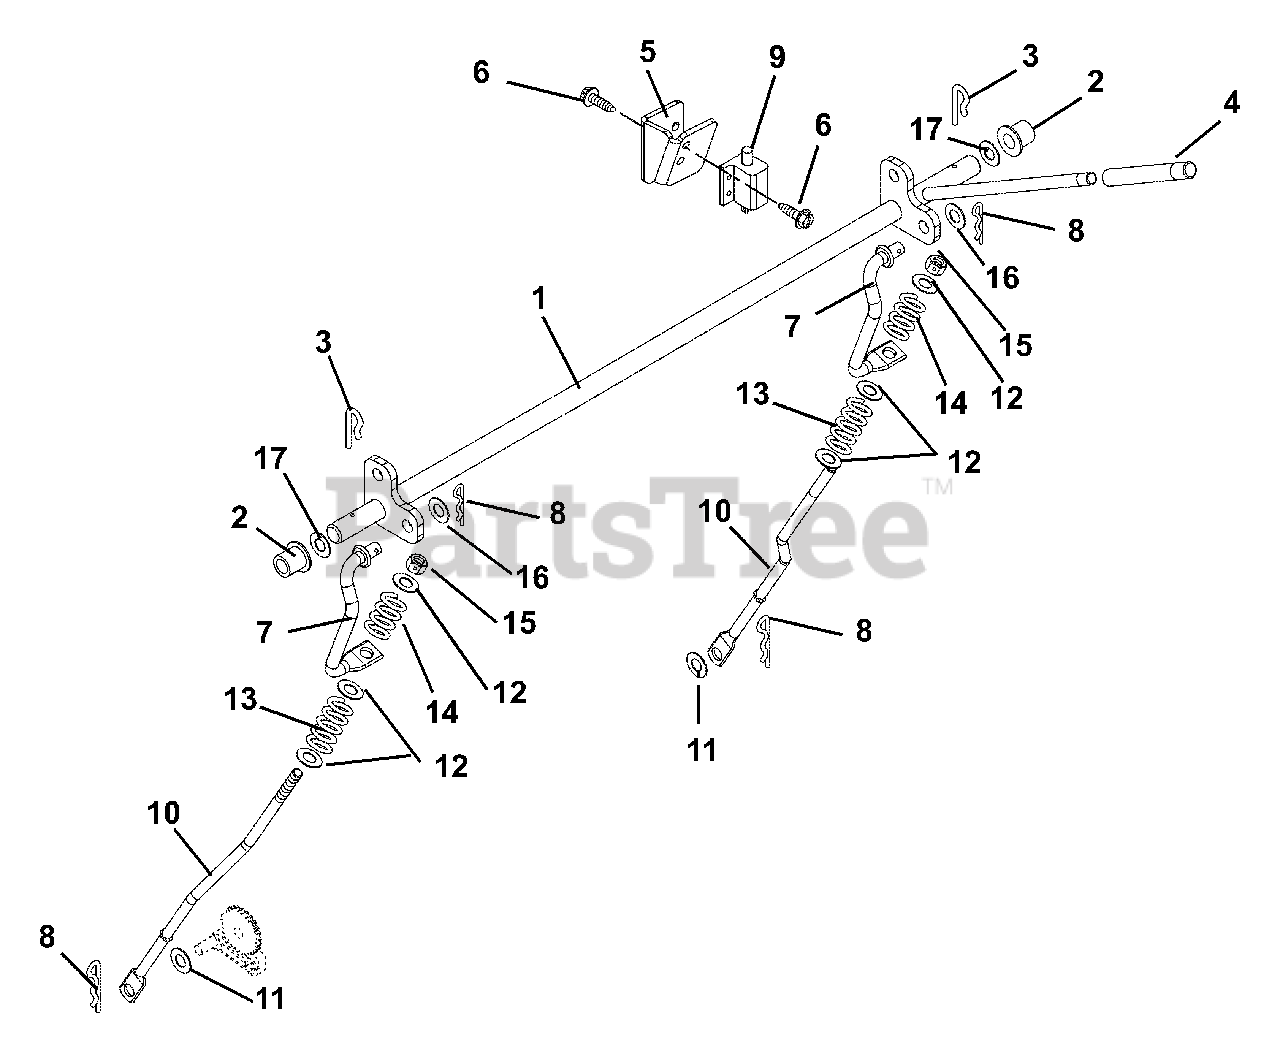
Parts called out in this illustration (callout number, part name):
1	WMT, ZOOM BRAKE ROD
2	BSHG-FLG .630X1.000X.625 NY
3	PIN, SPRING CLIP
4	GRIP,HAND CLUTCH LEVER
5	BRACKET, BRAKE SWITCH
6	@SCR-TAP 10-24X.50 HWH TR YWZC
7	ROD-OVER CENTER
8	PIN-HAIR, ENDRIES #25 YWZC
9	SWITCH,INTERLOCK
10	ROD-PARK BRAKE EZT
11	WSHR-FL-STL .406X1.00X.188 YWZ
12	@WSHR-FL-STL.344X.688X.065YWZC
13	SG-COMP .045X.50X1.187
14	SPRING, COMPRESSION
15	@NUT-LK-NYL .312-18 YWZC
16	@WSHR-FL-STL.406X.812X.065 YWZ
17	WSHR-FL-STL .627X.990X.032
